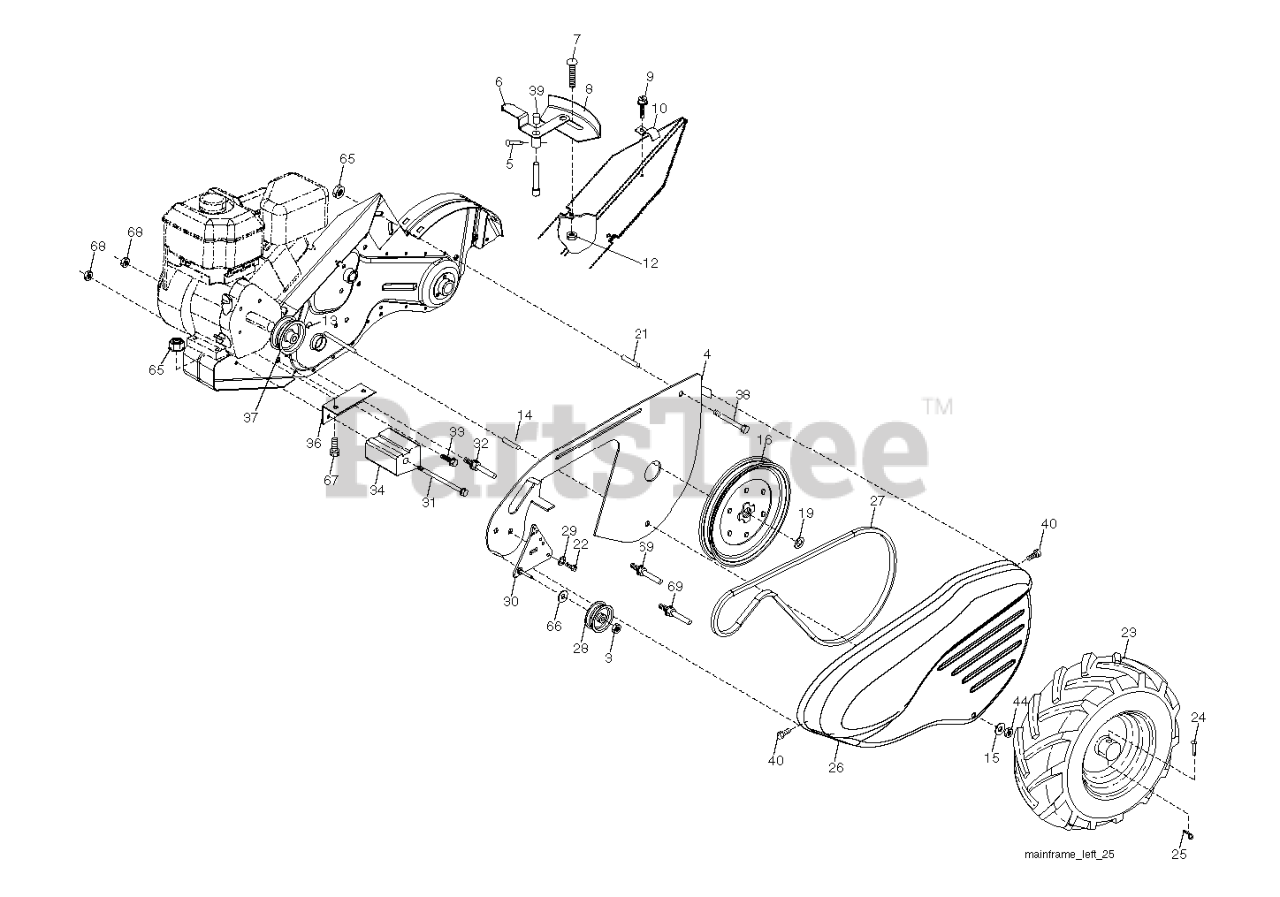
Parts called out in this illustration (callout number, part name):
3	NUT.HEX.3/8-16UNC
5	PIN.SPIROL.FLARED
6	LEVER ASM CRT
8	PANEL.INDICATOR.SHIFT.BLACK
9	TAPPING SCREW
10	CONDUIT.CLIP.PLATED
12	NUT
14	SPACER-SPLIT.327 X .42
15	WASHER
16	SHEAVE, TRANSMISSION
19	RETAINING RING LT
21	SPACER CRT
23	TIRE.16X4-8.CHEVRON.TILLER
24	RIVET,DRILLED
25	RETAINER M
26	RP BELT GUARD
27	V-BELT
28	PULLEY-IDLER TI
30	BRACKET.ASM.IDLER.BLACK
31	BOLT.FIN.HEX.3/8-16UNC
32	SHIFT ARM CRT
33	BOLT
34	COUNTERWEIGHT.LH.CRT
36	BRACKET LH CRT
37	RP.ENGINE PULLEY
38	BOLT
39	CAP.PLUNGER.BLACK
40	SCREW.HEX.WSH.SLT.#10-24X.50
44	NUT.71038.31-18.HEX.NYLOCK
65	LOCKNUT-FLANGE 5/16-18
66	WASHER
67	BOLT, HEX 5/16-18X1-3/4
